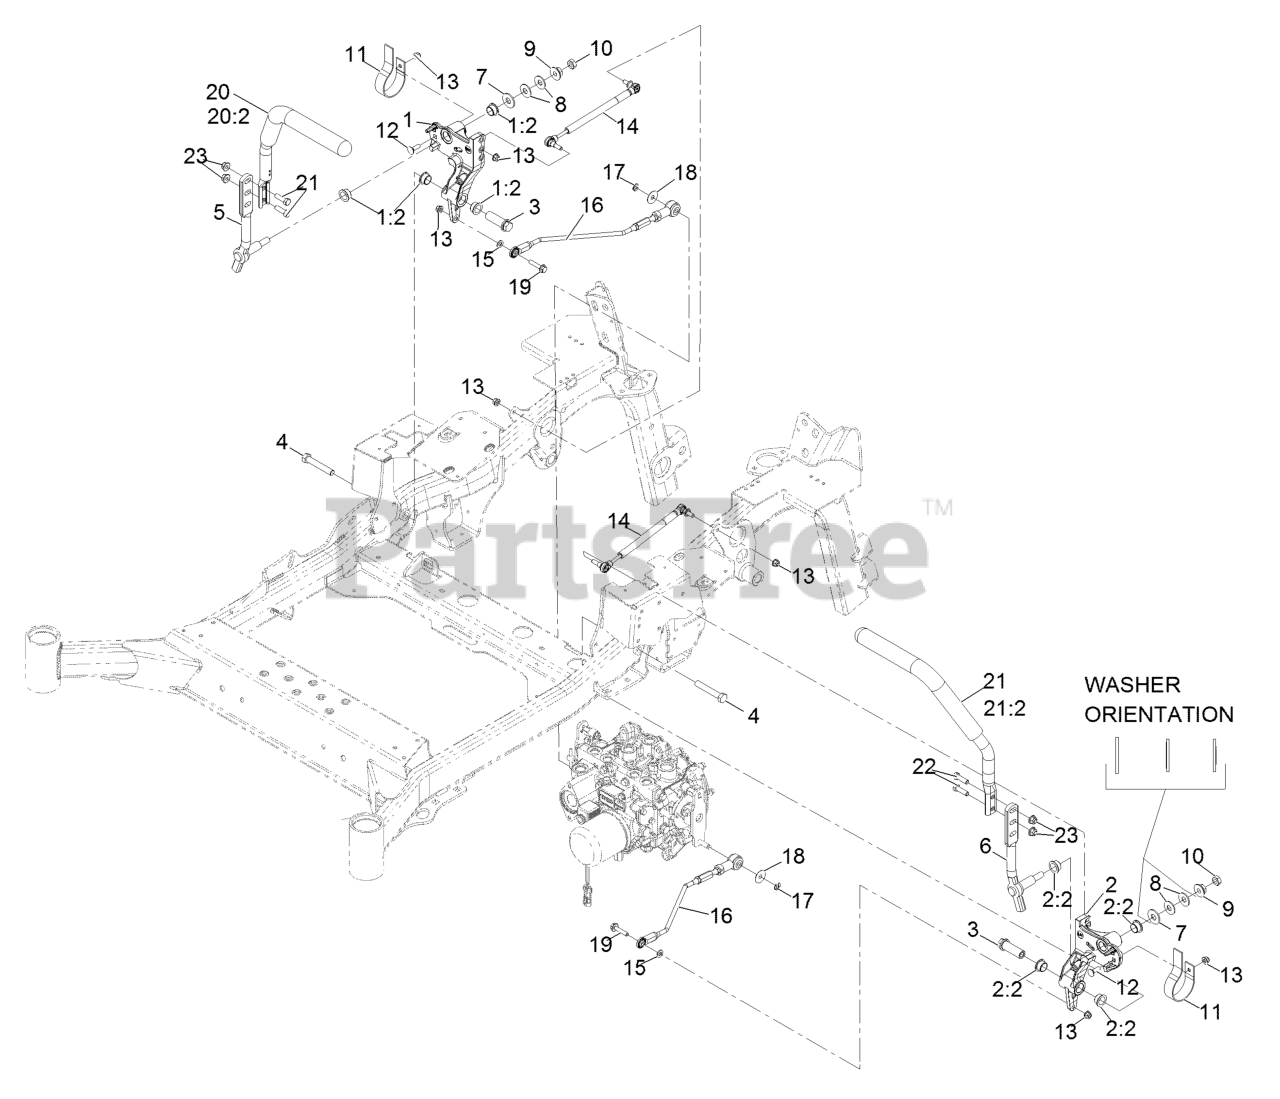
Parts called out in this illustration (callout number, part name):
1	RH Motion Control And Bushing ASM
1:2	Bushing-Flanged
2	LH Motion Control And Bushing ASM
2:2	Bushing-Flanged
3	Hub-Threaded
4	Screw-HH 1/2-13 X 3
5	Lever-Control Motion, RH
6	Lever-Control Motion, LH
7	Washer
8	Washer, Spring Disc 1/2
9	Nut-Hex 1/2-13 Flange
10	Nut-Jam 1/2-13
11	Spring-Leaf
12	Bolt-Carriage 5/16-18 X 1
13	Nut-Nyloc 5/16-18 Flg
14	Damper-Control, Motion
15	Washer-5/16 SAE
16	Front Linkage Rod ASM
17	Ring-Retaining
18	Washer-Plain
19	Screw-Hex Flange 5/16-18 X 1 1/2
20	RH Steering Handle ASM
20:2	Grip-Control, Lever
21	LH Steering Handle ASM
21:2	Grip-Control, Lever
22	Screw-HH 3/8-16 X 1 1/4
23	Nut-Nyloc 3/8-16 Flg
